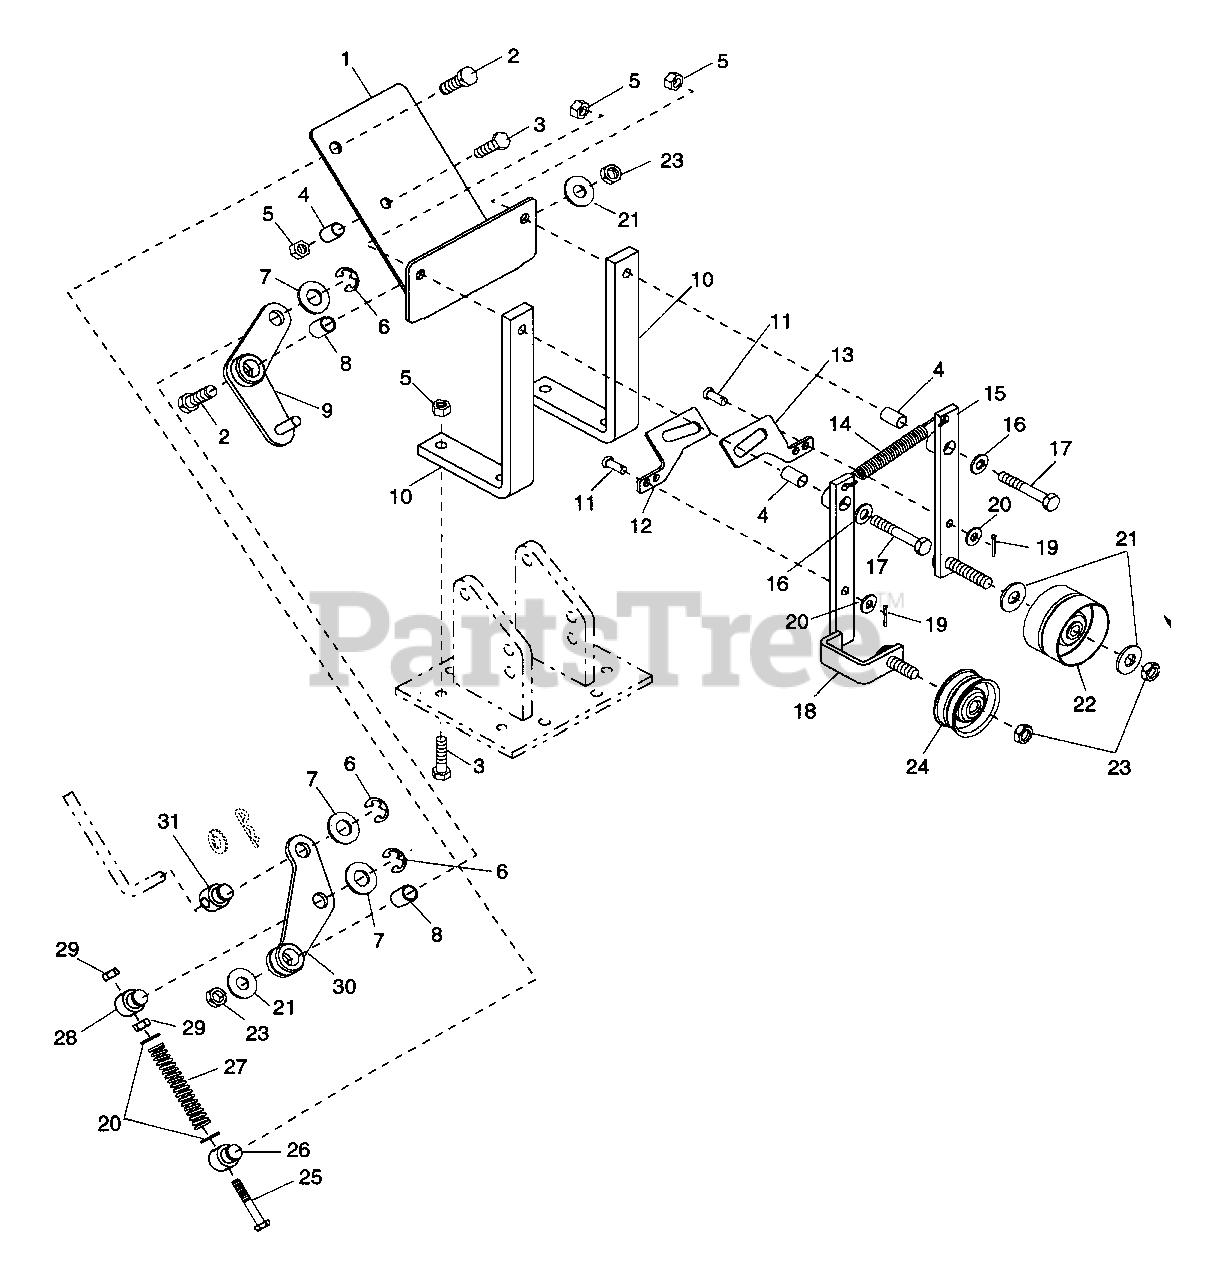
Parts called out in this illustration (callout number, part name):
1	SHIFTING PLATE
2	BLT-HEX .38-16X1.25 PL GR 2
3	BLT-HEX .31-18X1.25 PL GR2
4	SLEEVE BUSHING
5	NUT-LK .312-18 GR A PL
6	RG-RTNG-EXT .500X.042 (E)
7	WSHR-FL-STL .531X1.062X.095 PL
8	BSHG-SLV .406 X .545 X .68
9	BELLCRANK WELDMENT
10	SHIFT MTG BAR
11	CLEVIS PIN
12	SHIFT LINK - REVERSE
13	SHIFT LINK - FORWARD
14	SG-TENS .067X.437X3.25 WLD 4.5
15	IDLER ARM - FORWARD
16	WSHR-FL-STL.344X.688X.065PL
17	BLT-HEX .31-18X2.00 PL GR2
18	IDLER ARM - REVERSE
19	PIN-COTR .06X.50
20	WSHR-FL-STL.281X.62X.065 PL
21	WSHR-FL-STL .438X1.0X.083 PL
22	IDLER-FLAT 2.25 X .38
23	NUT-LK-JAM-CTR .375-16 PL
24	IDLER-FLAT 2.000X.375
25	BLT-HEX .25-20 X 4.5 PLATED
26	PIVOT - BELLCRANK
27	SG-COMP .080X.52X2.90
28	THREADED PIVOT - RODCRANK
29	NUT-HEX .250-20 PL
30	RODCRANK WELDMENT
31	PIVOT - SHIFT LEVER ROD
